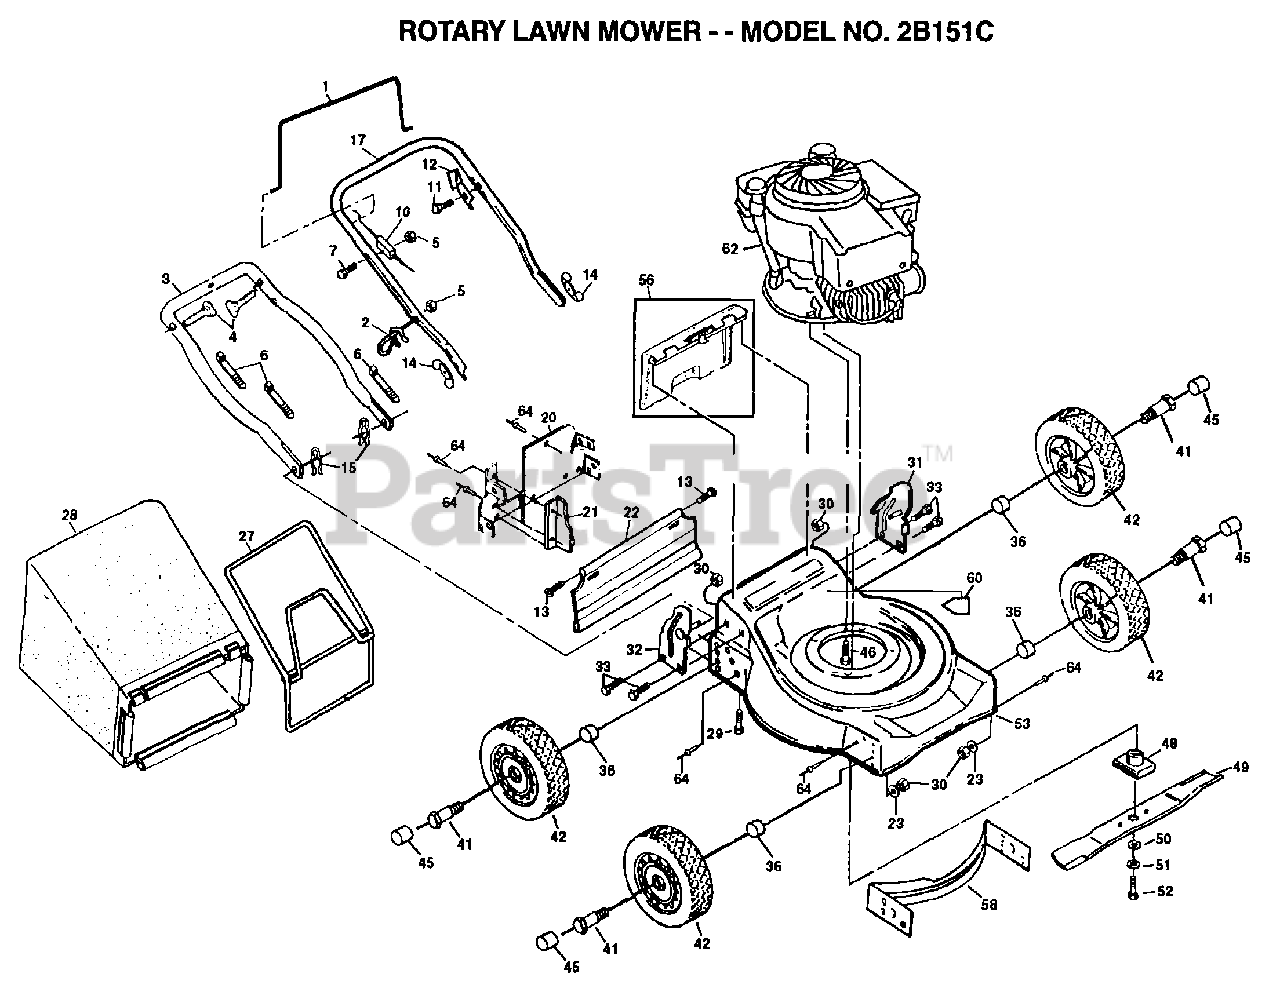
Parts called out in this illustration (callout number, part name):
1	CONTROL BAR PM
2	ROPE GUIDE
4	BOLT.HANDLE.LM
7	BOLT 1/4-20-1 1/2
10	"CABLE,ENG ZONE CO"
11	TAPPING SCREW
12	"BRKT,UPSTOP"
13	HINGE SCREW
14	"NUT,WING PM"
15	HAIRPIN COTTER
20	PLATE.BACK.20RD
22	SKIRT.REAR.20RD.
23	WASHER PM
27	FRAME.CATCHER.ASM
28	GRASS BAG
29	SCREW
30	LOCKNUT PM
33	SCREW
41	AXLE BOLT
42	WHEEL.ASM
45	HUB CAP-PLASTIC
46	SCREW
48	BLADE ADAPTOR
49	BLADE.20.MULCH.AY
50	"WASHER,HARDEN"
51	LOCKWASHER
52	SCREW
53	KIT.HSG.20RD.PUSH
56	KIT.DOOR.RR.20STL
60	DECAL HYT
64	BLIND RIVET
